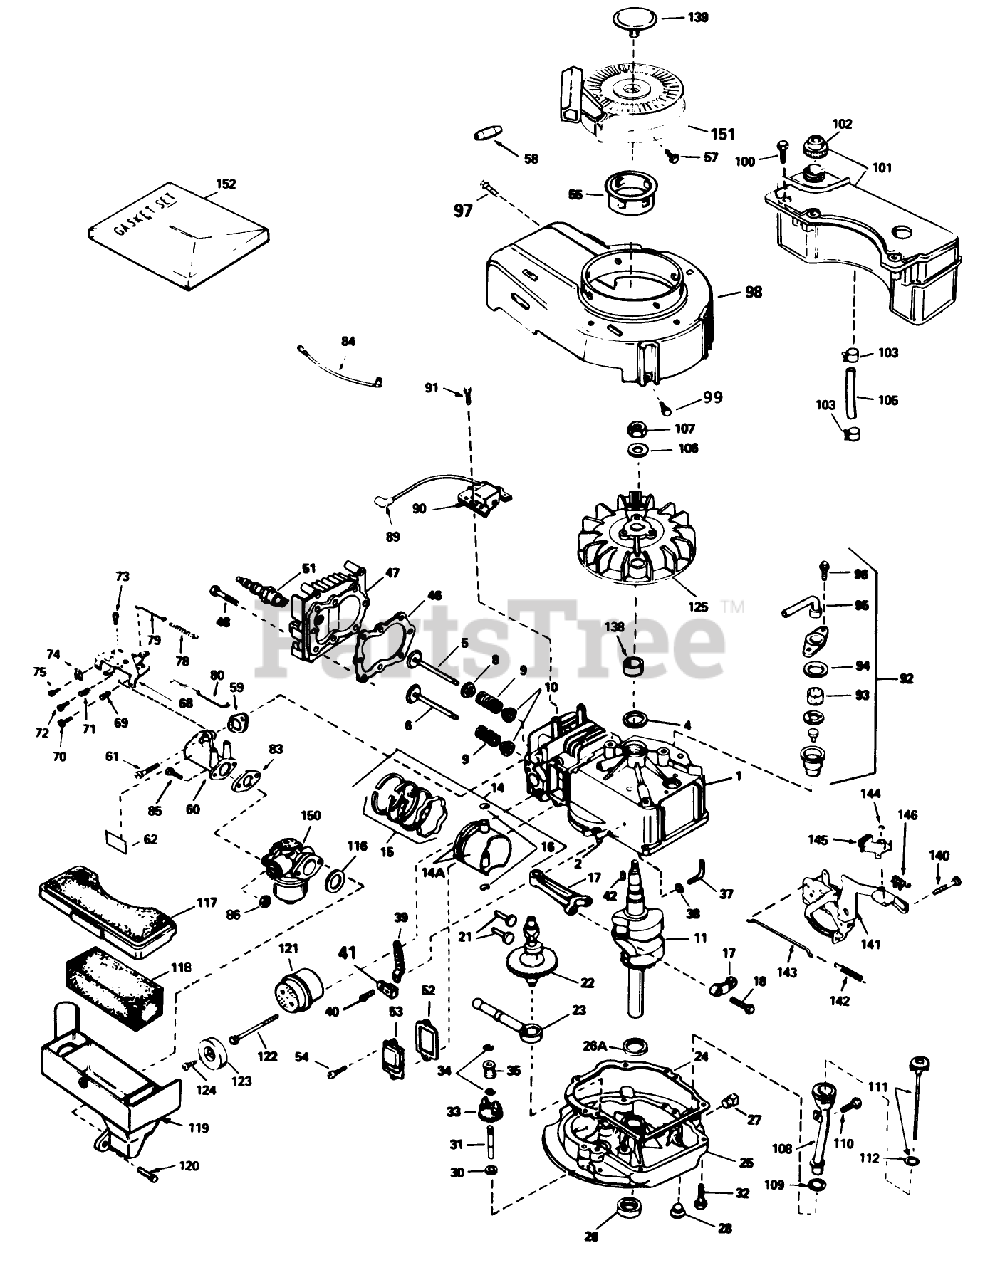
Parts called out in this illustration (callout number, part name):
1	Cylinder Assy. (Incl. #24)
2	Pin-Dowel
4	Seal-Oil
5	Valve, Intake (Std.) (Incl. Ref. #40)
5	Valve, Intake (1/32" oversize)(Incl. No. 40)
6	Valve, Exhaust (Std.)(Incl. No. 40)
6	Valve, Intake (1/32" oversize)(Incl. No. 40)
8	Seal Assy., Intake
9	Spring-Valve
10	Cap-Valve, Spring
11	Crankshaft
14	Piston, Pin Ring Assy. (Std.) (Incl. Ref. #13A, 14 15)
14	Piston, Pin Ring Assy. (.010 oversize) (Incl. Ref. #13A, 14 15)
14	Piston, Pin Ring Assy. (.020 oversize) (Incl. Ref. #13A, 14 15)
14A	Piston Pin Assy. (Incl . Ref. . #14) (Std.)
14A	Piston Pin Assy. (Incl. Ref. #14) (.010 Oversize)
14A	Piston Pin Assy. (.020 oversize) (Incl. Ref. #14)
15	Ring Set (Std.)
15	Ring Set (.020" OS)
15	Ring Set (.010" OS)
16	Ring-Retaining, Piston Pin
17	Rod Assy., Connecting (Incl. Ref. #17)
18	Bolt-Rod, Connecting
21	Lifter-Valve
22	Camshaft(Mech.Comp. Release)
23	Oil Pump ASM
24	Gasket
25	Flange-Mounting (Incl. Ref. #26, 27 39)
26	Seal-Oil
26A	Washer-Thrust
28	Plug Oil Drain
30	Washer-Flat
31	Shaft-Governor
32	Screw (1/4-20 x 1-1/4)
33	Governor Gear ASM
34	Ring-Retaining
35	Spool-Governor
37	Rod, Governor (Incl. No. 36)
38	Washer-Flat
39	Governor Lever
40	Screw
41	Clamp-Lever, Governor
42	Key-Flywheel
46	63573 GIL 42 SNWTHW
47	Head-Cylinder
48	Screw (5/16-18x1-1/2)
51	Plug, Spark (Autolite 458, Champion J-19LM or equiv.)
52	Gasket-Breather
53	Cover-Valve
54	Screw
55	Hub-Starter
57	Screw, Hex Hd.
58	Retainer-Starter Rope
59	Gasket-Intake
60	Pipe-Intake (Incl. Ref. #59)
61	Screw (1/4-20 x 1)
62	Decal-Primer
68	Control Assy.-Remote Speed (Incl. Ref. #69 thru 72 76)
69	61709/GIL1515A/95-5
70	Screw
71	Spring-Compression
72	Screw
73	Screw (10-24 x 9/16)
74	Conduit
75	Screw (10-32 x 3/8)
78	Spring Governor
79	2035A67 ADD.ASSEMBL
80	Link-Throttle
83	Gasket
84	Ground Wire
86	Nut and Lock Washer (1/4-28)
89	Cover-Spark Plug
90	Solid State
91	Screw
92	Breather Assy. (Incl. Ref. #46 thru 51)
93	Element-Breather
94	Gasket-Breather
95	Tube, Breaker
96	Screw (10-24 x 9/16)
97	Screw (10-24 x 9/16)
98	Housing-Blower
99	Screw (1/4-20 x 1/2)
100	Screw (10-32 x 35/64)
101	Tank Assembly-Fuel (Incl. Ref. #102)
102	Cap-Fuel
103	Clamp-Line, Fuel
105	Line-Fuel
106	Washer-Belleville
107	Nut-Flywheel
108	Tube-Oil Fill
109	Gasket
110	Screw (10-32 x 1/2)
111	Dipstick-Oil (Incl. Ref. #112)
112	O-Ring
116	Gasket-Cleaner, Air
117	Cover-Air Cleaner
118	Filter-Air Cleaner
119	Body Air cleaner
120	Screw
121	B Muffler (Incl. Ref. #122)
122	Screw
123	Cover-Muffler
124	Screw (8-32 x 3/8)
125	Flywheel
138	Spacer
139	Plug Starter
140	Screw (1/4-20 x 3/8)
141	Bracket-S.E. Brake
142	Spring-Extension
143	Link-Control
144	Ring-Retaining
145	Lever-Brake
146	Terminal
150	Carburetor (Incl. Ref. #83)
151	Starter-Rewind
152	Gasket Set
